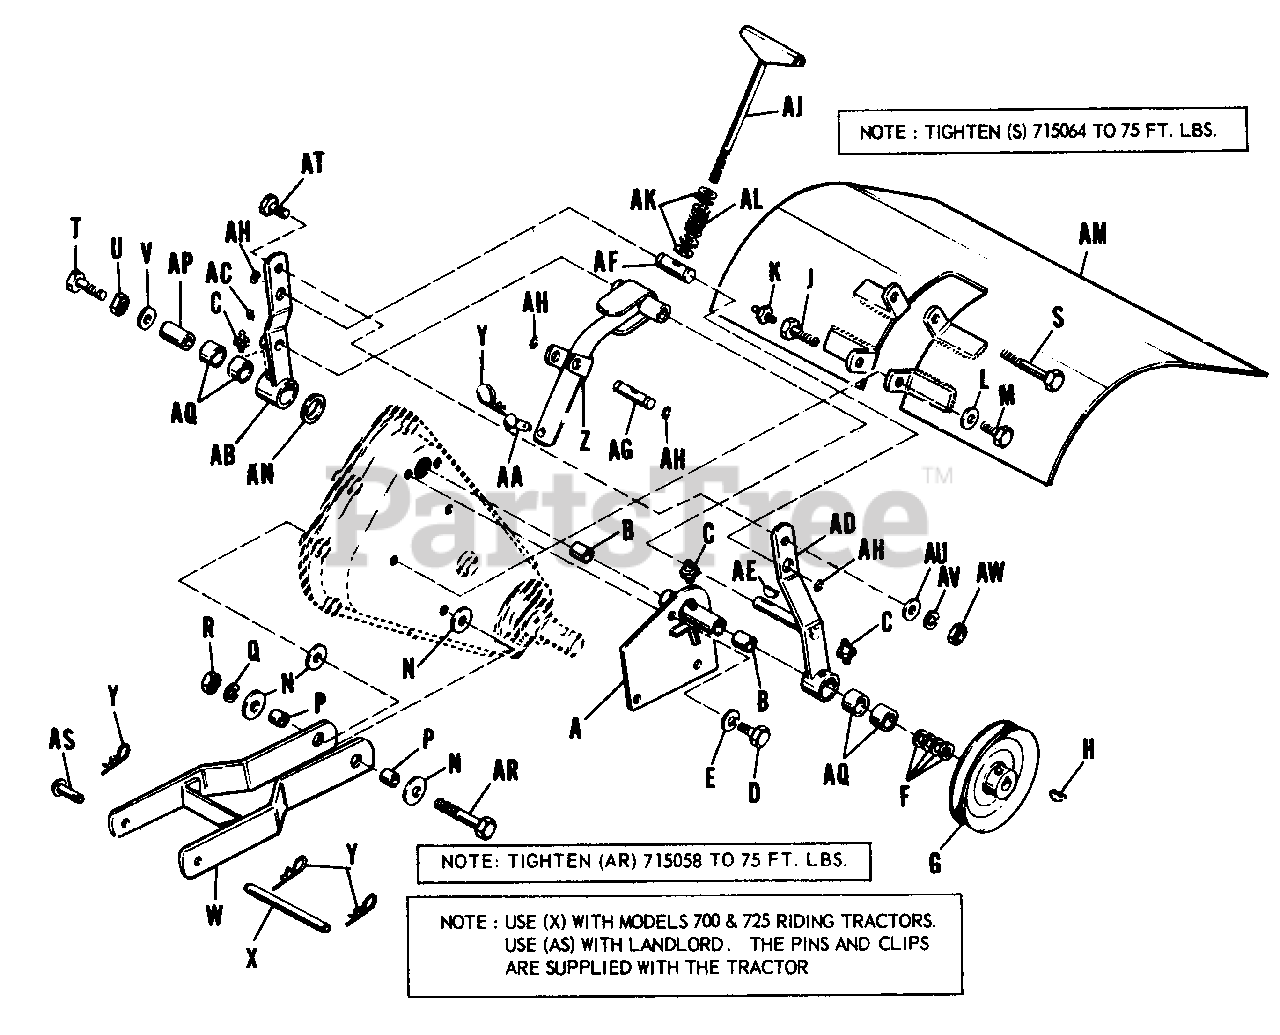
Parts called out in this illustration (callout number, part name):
A	Support Assembly, Brg. Hsg.
B	Bearing, Needle
C	Fitting, Grease
D	Capscrew, Hex, 5/16"-18 NC x 3/4" lg.
E	Washer, Lock 5/16"
G	Pulley, Drive
H	Key, Woodruff
K	Fitting, Grease
L	Washer, Plain, 7/16"
M	Capscrew, Hex, 1/2"-20 NF x 1-3/4" lg.
Q	Washer, Lock 7/16"
R	Nut, Hex, Full 7/16"-14 NC
S	Capscrew 7/16"-14 NC x 4" lg.
T	Capscrew 3/8"-24 NF x 2-1/2" lg.
U	Nut, Hex, Jam-3/8"-24 NF
V	Washer, Plain, 3/8"
W	Frame Assembly
X	Rod, Pivot
Y	Clip, Spring
Z	Bar, Assembly, Lift
AA	Pin
AB	Lever Assembly, R.H., Belt Tension
AC	Screw, Set, Cup Pr., Socket Hd. 5/16"-18 NC x 2/16" lg.
AD	Lever Assembly, L.H. Belt Tension
AE	Key Woodruff #6
AF	Pivot, Upper
AG	Pivot, Lower
AH	Ring, Retaining
AJ	Screw Assembly, Adjusting
AK	Washer Plain 5/16"
AM	Deflector Assembly
AN	Washer Thrust
AR	Capscrew Hex, 7/16"-14 NC x 4-1/2" lg.
AT	Capscrew, Hex, 3/8"-16 x 1" lg.
AU	Washer, Plain 3/8"
AV	Washer, Lock 3/8"
AW	Nut, Hex, Full, 3/8"-16
